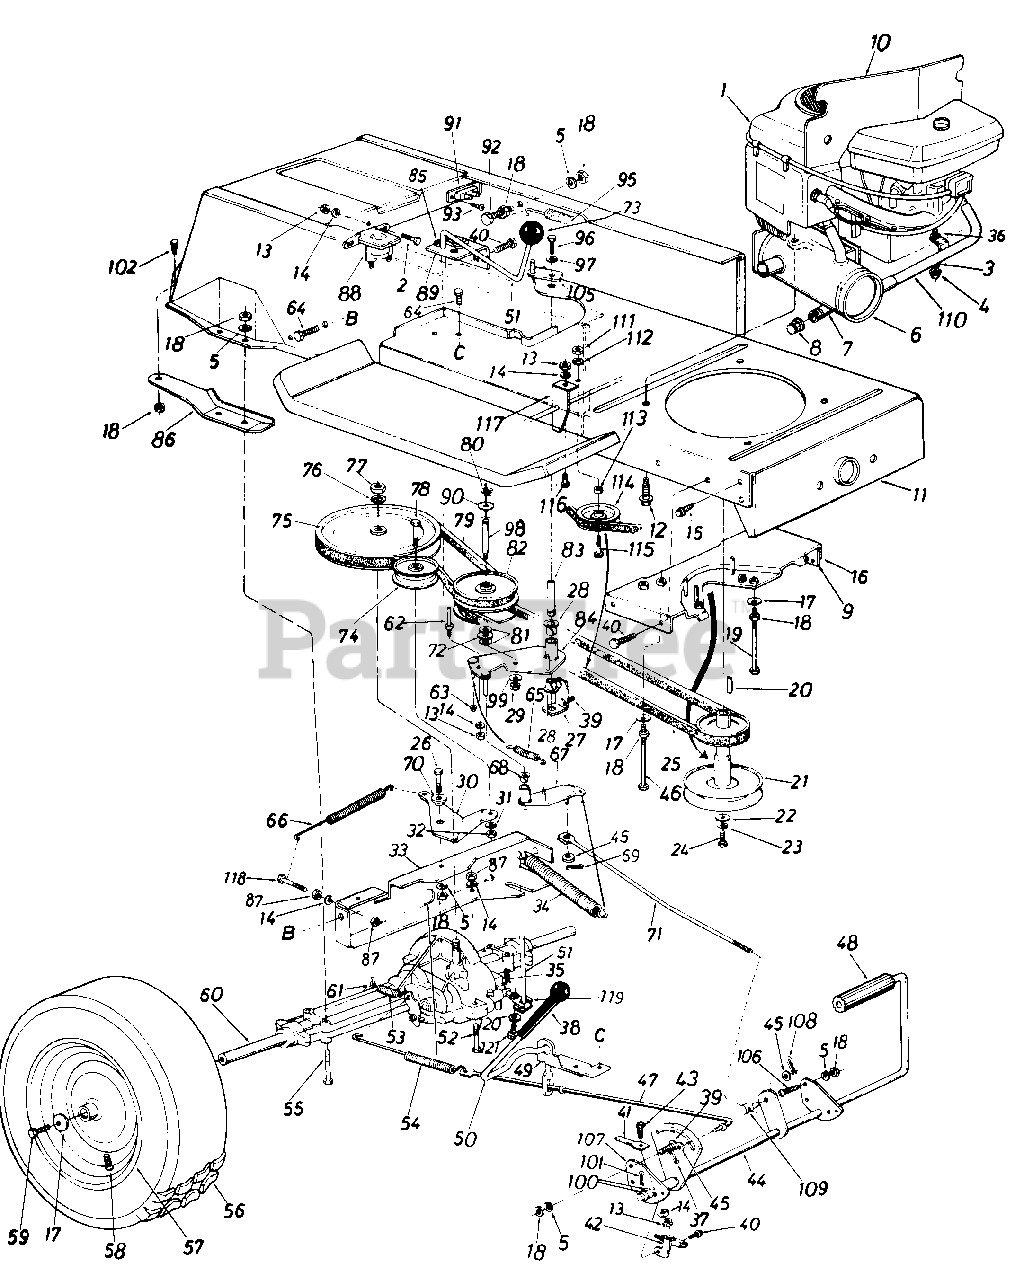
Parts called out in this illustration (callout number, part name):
1	Engine
2	Hex Bolt 1/4-20 x .62" Lg.*
3	Special L-Wash. 5/16" I.D.
4	Hex Nut 5/16-18 Thd.
5	L-Wash. 5/16" I.D.
6	Exhaust Muffler
7	Pipe Nipple
8	Cap Oil Drain
9	Brake Cable Brk't.
10	Heat Shield
11	Lower Frame Ass'y.
12	Hex Wash Hd TT-Tap Scr 3/8-16 x 1.25" Lg.
13	Hex Nut l/4-20 Thd.
14	L-Wash . 1/4 " 1. D .
15	Hex Wash. Hd. AB-Tap Scr. 5/16" x .75" Lg.
16	Belt Guard Brkt. Ass'y.
17	Bell-Wash. .345" I.D. x .88"
18	Hex Nut 5/16-18 Thd.
19	Hex Bolt 5/16-18 x 4.00"
20	Sq. Key 1/4" x 1/4" X 2.00"
21	Engine Pulley
22	Fl-Wash. 7116" I.D. x 1.25"
23	L-Wash. 7116" I.D.
24	Hex Bolt 7/16-20 x 1.50" Lg.
25	Variable-Speed Belt
26	Hex Bolt 5/16-18 x .75" Lg.
27	Bearing Shaft Bracket Ass'y.
28	Flanged Nyliner Brg. 518" I.D. x .88" Lg.
29	Hex Nut 3/8-24 Thd.*
30	Idler Bracket
31	L-Wash. 3/8" I.D.
32	Hex Nut 3/8-24 Thd.*
33	Transaxle Support Brkt.
34	Ext. Spring .94" O.D. x 6.7
35	Inter. Cotter Pin
36	Fl-Wash. .34" I.D. x .62" O.D. x .033
37	Cotter Pin 3/32" Dia. x .75"
39	Truss Mach. Scr. 5/16-18 x .75" Lg.
40	Hex Wash. Hd. Self-Tap Scr. 1/4-20 x .50" Lg.
41	Switch Actuator
42	Safety Switch
43	Hex Bolt 1/4-20 x 1.0" Lg.
44	Clutch & Brake Pedal Ass'y.
45	Fl-Wash.
46	Hex Bolt 5/16-18 x 4.5"*
47	Brake Rod 20.9" Lg.
48	Foot Pad
49	Brake Lever Bracket
50	Hill Holder Brake Handle
51	Shift Lever Ass'y.
52	Hex Bolt 1/4-28 x 1.75" Lg.
53	Ext. Spring .38" O.D. x 2.5"
54	Ext. Spring .59" O.D. x 7.08"
55	Hex Bolt 5/16-18 x 2.75"
58	Air Valve
59	Hex Bolt 5/16-24 x .75" Lg.
60	Transaxle Complete-R.H.
61	Brake Return Spring Anchor
62	Belt Guard Pin 1/4-20 Thd.
63	Cap Speed Nut 1/4" Dia.
64	Hex Wash. TT-Tap Scr. 5/16 x .62" Lg.
65	Ext. Spring .50" Dia.
66	Ext. Spring .62" O.D. x 6.1 2"
67	Variable Speed Torque Brkt. Ass'y.
68	Flanged Bearing
69	Cotter Pin 3/32" Dia.
70	Shoulder Spacer .500" Dia. x.27" Lg.
71	Speed Control Link
72	Truss Bearing .56 Dia. x 1 .25"
73	Ball Knob
74	Fl-ldler Pulley 3.25" x 1.0
75	1/2" "V"-Pulley 8.0" O.D. x.501" I.D.
76	L-Wash. 1/2" I.D.*
77	Hex Jam Nut 1/2-20 Thd.
78	Hex Bolt 3/8-24 x .75" Lg.
79	Variable Speed Belt
80	Snap Ring .56" Dia.
82	Variable Speed Pulley Ass'y. 5" O.D.
83	Bearing Shaft
84	Variable Speed Brkt. Ass'y.
85	Comp. Spring Clip
86	Transaxle Support Brkt.-R.H.
87	Hex Nut 1/4-28 Thd.
88	Solenoid
89	Shift Lever Bracket
90	Teflon Washer
91	Circuit Breaker
92	Hex Bolt 5/16-18 x 1.50"
93	Truss Hd. Phil. Scr. #10 x 1/2 " Lg
95	Ext. Spring .99" O.D. x 11.0"
96	Hex Bolt 3/8-24 x .75" Lg.
97	Bell-Wash. .38" I.D. x .88"
98	Shaft .56" Dia. x 3.875" Lg.
99	Bell-Wash. .39" I.D. x 1.12"
100	Fl-Wash.
101	Cotter Pin 3/32" Dia. x .75"
102	Hex Wash. Hd. Scr. 5/16-18 x.62" Lg.
105	Belt Guard
106	Hex Bolt 5/16-18 x .751' Lg.
107	Pedal Bracket
108	Cotter Pin 3/32 x .75"
109	Ferrule
110	Inlet Tube Ass'y.
111	Hex Nut 3/8" 16 Thd.
112	L-Wash. 3/8" I.D.*
113	Fl-Wash. .390" I.D. x 1.12"
114	Fl-ldler w/Flanges 2.750
115	Hex Bolt 3/8-16 x 2.00" Lg.*
116	Hex Bolt 1/4-20 x .62" Lg.*
117	Spring Hanger Bracket
118	Hex Bolt 1/4-28 x 1.25" Lg.*
119	Shift Lever Link Ass'y.
120	Bell-Wash. .265 I.D. x .75 O.D.
121	Hex Bolt 1/4-28 x .62" Lg.
